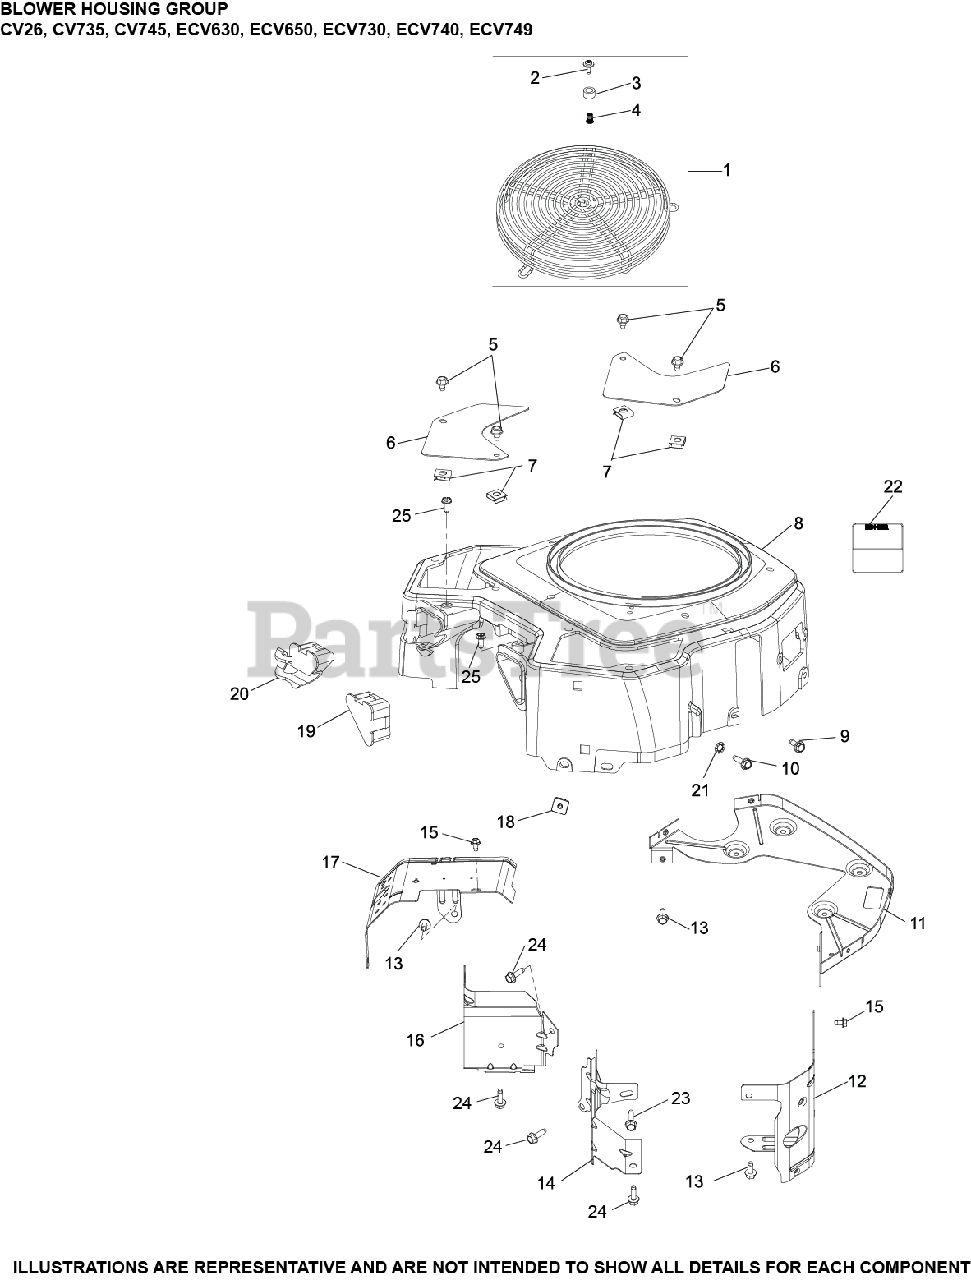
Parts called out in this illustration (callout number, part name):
2	SCREW, SEMS
3	SPACER USE 25 112 30-S
4	INSERT, THREADED USE 25 332 19-S
5	SCREW, THREAD FORMING
6	KIT, ACCESS PANEL
7	CLIP, BAFFLE MOUNTING
8	HOUSING, BLOWER
9	SCREW, THREAD FORMING
11	PLATE, BACKING
12	BAFFEL, LEFT BARREL
13	SCREW, THREAD FORMING
14	BAFFLE, VALLEY #2 CYLINDER
15	SCREW, THREAD FORMING
16	BAFFLE, VALLEY #1 CYLINDER
17	BAFFLE, RIGHT BARREL
20	COVER, BLOWER HOUSING-MOLDED USE 24 096 161-S
23	SCREW, THREAD FORMING
24	SCREW, THREAD FORMING
25	SCREW, WSH HD TAP #8-18X1/2"
